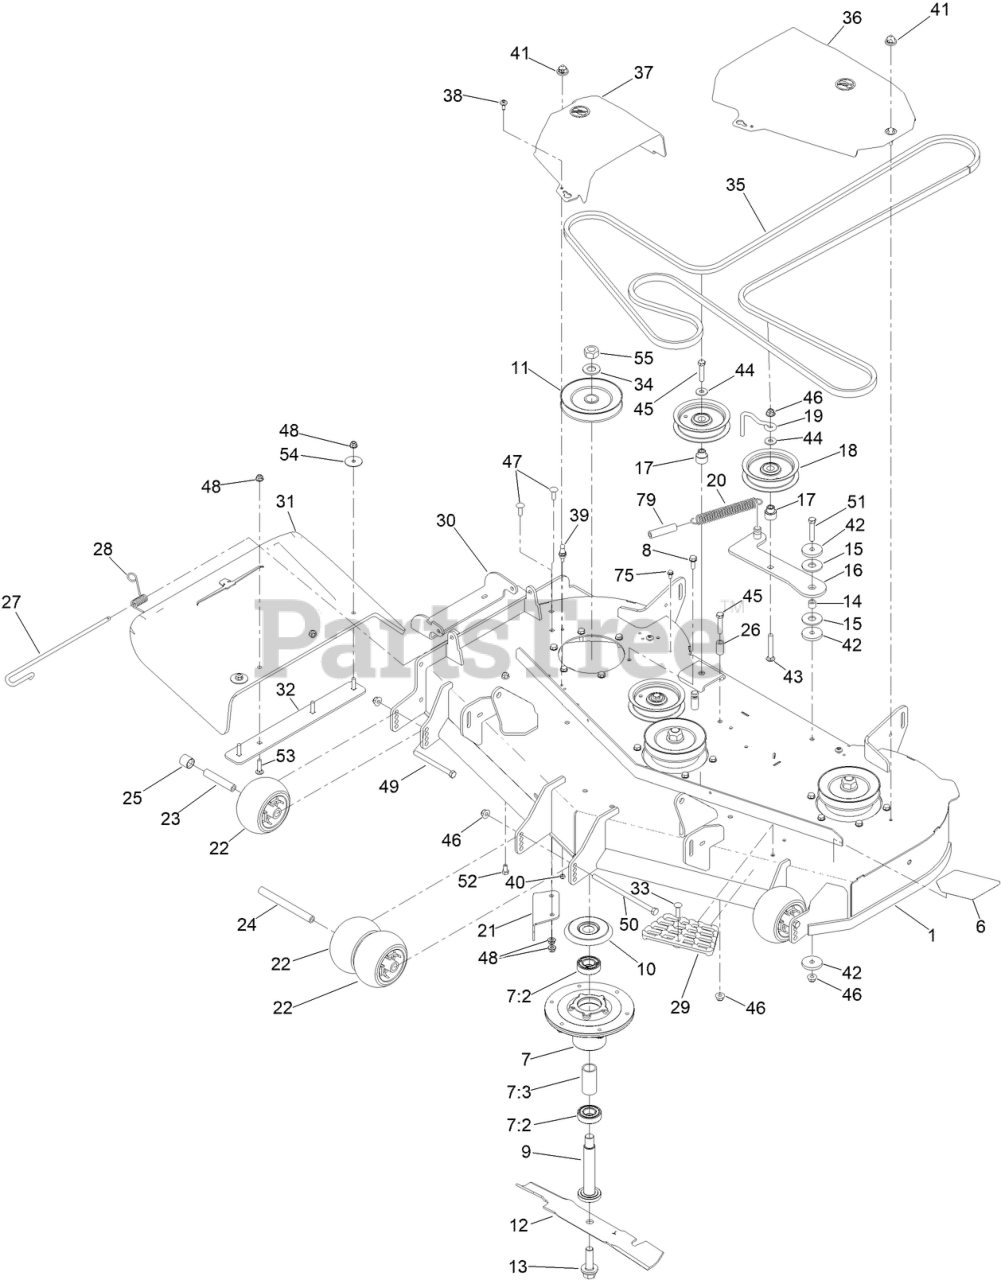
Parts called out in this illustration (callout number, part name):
1	48 IN DECK DECAL ASM
6	DECAL - DECK 48
7	SPINDLE ASM
7:2	BEARING-BALL
7:3	SPACER-BEARING
8	SCREW-TAPTITE
9	SHAFT-SPINDLE
10	SHIELD-BEARING
11	PULLEY
12	BLADE-HI FLO, 16.50 INCH
13	SCREW-BLADE
14	SPACER
15	WASHER-FRICTION, COMPOSITE
16	IDLER ARM ASM
17	BUSHING-IDLER
18	PULLEY-IDLER, FLAT
19	GUIDE-BELT, IDLER
20	SPRING-EXTENSION
21	BAFFLE-CUTOFF
22	ROLLER-SCALP, ANTI
23	TUBE-SPANNER
24	SPACER-WHEEL
25	SPACER-AXLE, REAR
26	SPACER-FENDER
27	PIN-CHUTE
28	SPRING-TORSION
29	STEP-DECK
30	BRACKET-DEFLECTOR, UPPER
31	DEFLECTOR - MOLDED
32	PLATE-DEFLECTOR
33	BOLT-CARRIAGE
34	WASHER
35	V-BELT
36	COVER-BELT, LH
37	COVER-BELT, RH
38	SCREW-SHOULDER
39	STUD-BALL
40	NUT-LOCK
41	GROMMET-BALL
42	WASHER-PLAIN
43	SCREW-CARR
44	WASHER-HARDENED
45	SCREW-HH
46	NUT-HF, NI
47	SCREW-CARR
48	NUT-HF, NI
49	SCREW-HH
50	SCREW-HH
51	SCREW-HH
52	SCREW-HH
53	SCREW-CARR
54	WASHER-FLAT
55	NUT-HEX
75	SCREW-HWH
79	HOSE-BREATHER
